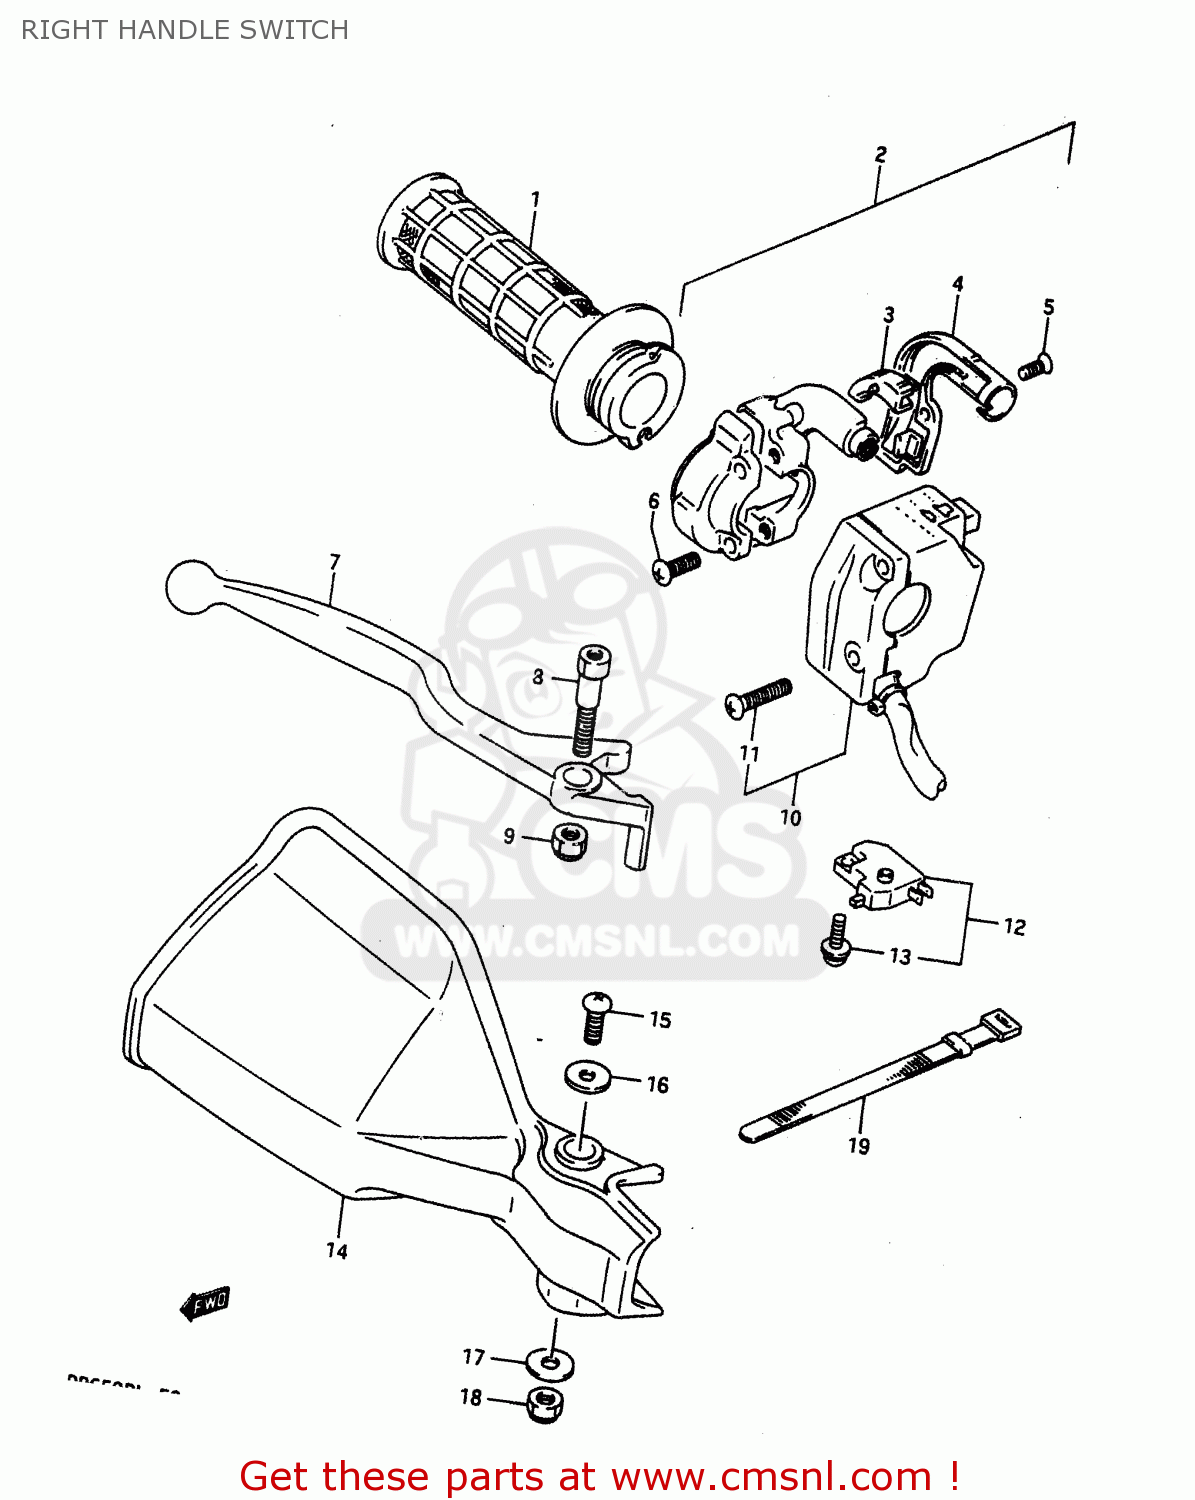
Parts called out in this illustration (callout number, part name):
1	GRIP,THROTTLE
2	CASE ASSEMBLY,THROTTLE
3	GUIDE PIECE,THROTTLE
4	COVER,THROTTLE CASE
5	SCREW 4X10
6	SCREW
7	LEVER,BRAKE
8	BOLT,BRAKE LEVER PIVOT
9	NUT 6MM
10	SWITCH ASSY, HANDLE RH
11	SCREW(5X25)
12	SWITCH ASSEMBLY,STOP
13	SCREW
14	COVER,KNUCKLE,RIGHT
15	SCREW(5X10)
16	WASHER (5.5X16X1.2)
17	WASHER (6.5X17X1.6)
18	NUT 6MM
19	CLAMP(L:120)
